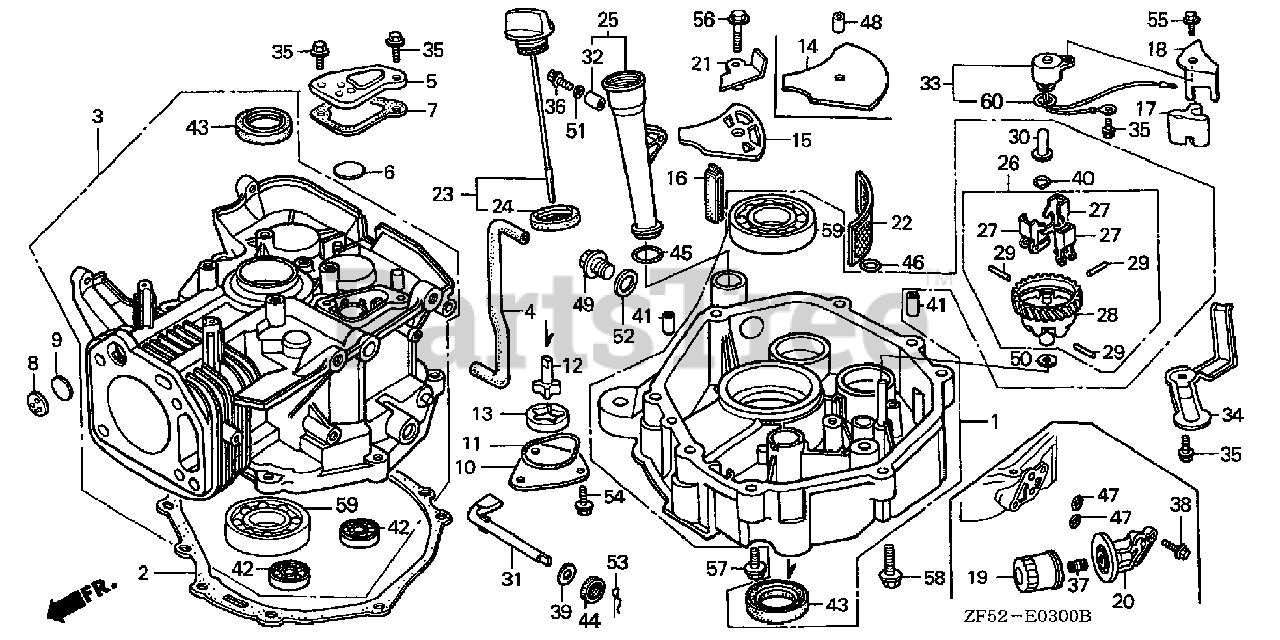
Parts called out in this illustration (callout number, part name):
1	PAN ASSY., OIL
2	GASKET, OIL PAN
3	CYLINDER ASSY.
4	TUBE, BREATHER
5	CAP, BREATHER CHAMBER
6	VALVE, BREATHER
7	GASKET, BREATHER CAP
10	COVER, OIL PUMP
11	O-RING, PUMP COVER
12	ROTOR (INNER)
13	ROTOR, OIL PUMP (OUTER)
14	PLATE, OIL FILTER
16	RUBBER, OIL RETURN
22	SCREEN, OIL FILTER
23	CAP ASSY., OIL FILLER
24	GASKET, OIL FILLER CAP
25	EXTENSION, OIL FILLER
26	GOVERNOR ASSY.
27	WEIGHT, GOVERNOR
28	HOLDER, GOVERNOR WEIGHT
29	PIN, GOVERNOR WEIGHT
30	SLIDER, GOVERNOR
31	SHAFT, GOVERNOR ARM
32	COLLAR, EXTENSION
35	BOLT, FLANGE (6X12) (CT200)
36	BOLT, FLANGE (6X35) (CT200)
39	WASHER, THRUST (8.1MM)
40	CLIP, GOVERNOR HOLDER
41	PIN, DOWEL (8X12)
42	BEARING, RADIAL BALL (6202)
43	OIL SEAL (35X52X8)
44	OIL SEAL (8X14X5)
45	O-RING (22.1X2.2)
46	O-RING (11.8X2.4)
48	COLLAR, OIL FILTER SETTING
49	BOLT, DRAIN PLUG (20MM)
50	WASHER, PLAIN (6MM)
51	WASHER, PLAIN (6MM)
52	WASHER, DRAIN PLUG (20MM)
53	PIN, LOCK (10MM)
54	BOLT, FLANGE (6X12)
56	BOLT, FLANGE (6X25)
57	BOLT, FLANGE (8X40)
58	BOLT, FLANGE (8X60)
59	BEARING, RADIAL BALL (6207)
